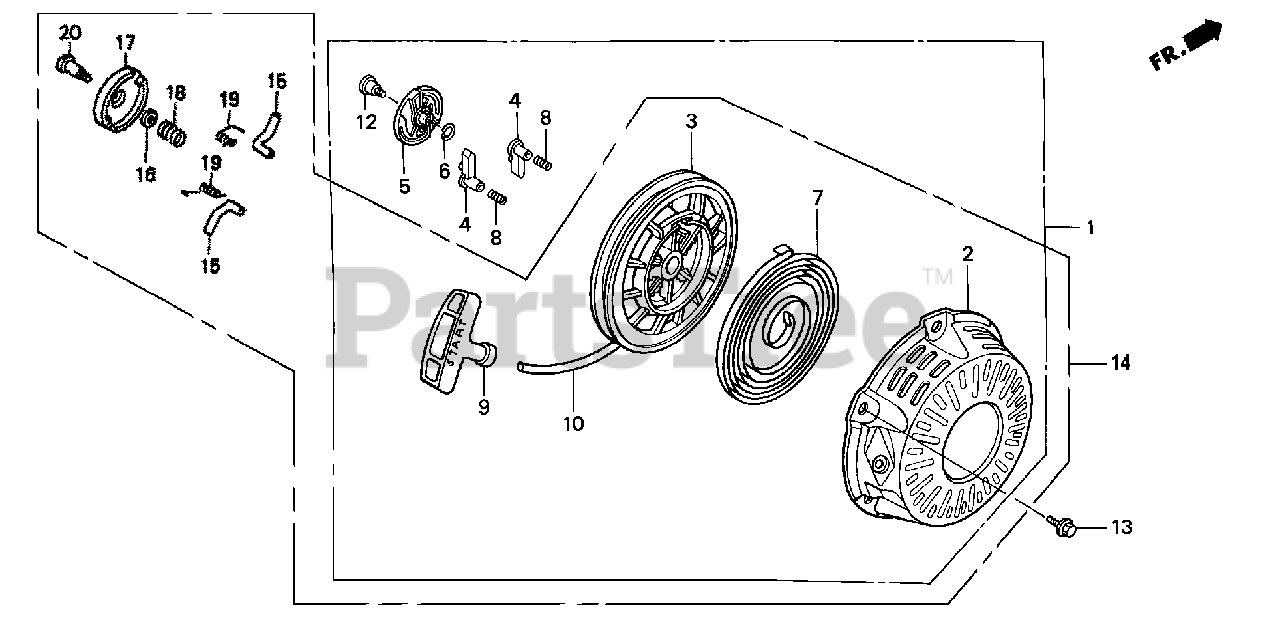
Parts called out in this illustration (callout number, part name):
1	STARTER ASSY., RECOIL *R280* (POWER RED)
2	CASE, RECOIL STARTER *R280* (POWER RED)
3	REEL, RECOIL STARTER
4	RATCHET, STARTER
5	GUIDE, RATCHET
6	SPRING, FRICTION
7	SPRING, RECOIL STARTER
8	SPRING, RETURN
9	KNOB, RECOIL STARTER
10	ROPE, RECOIL STARTER (#5X55")
12	SCREW, SETTING
13	BOLT, FLANGE (6X10)
14	STARTER ASSY., RECOIL *R280* (POWER RED)
15	RATCHET, STARTER
16	PLATE, FRICTION
17	GUIDE, RATCHET
18	SPRING, FRICTION
19	SPRING, RETURN
20	SCREW, SETTING
